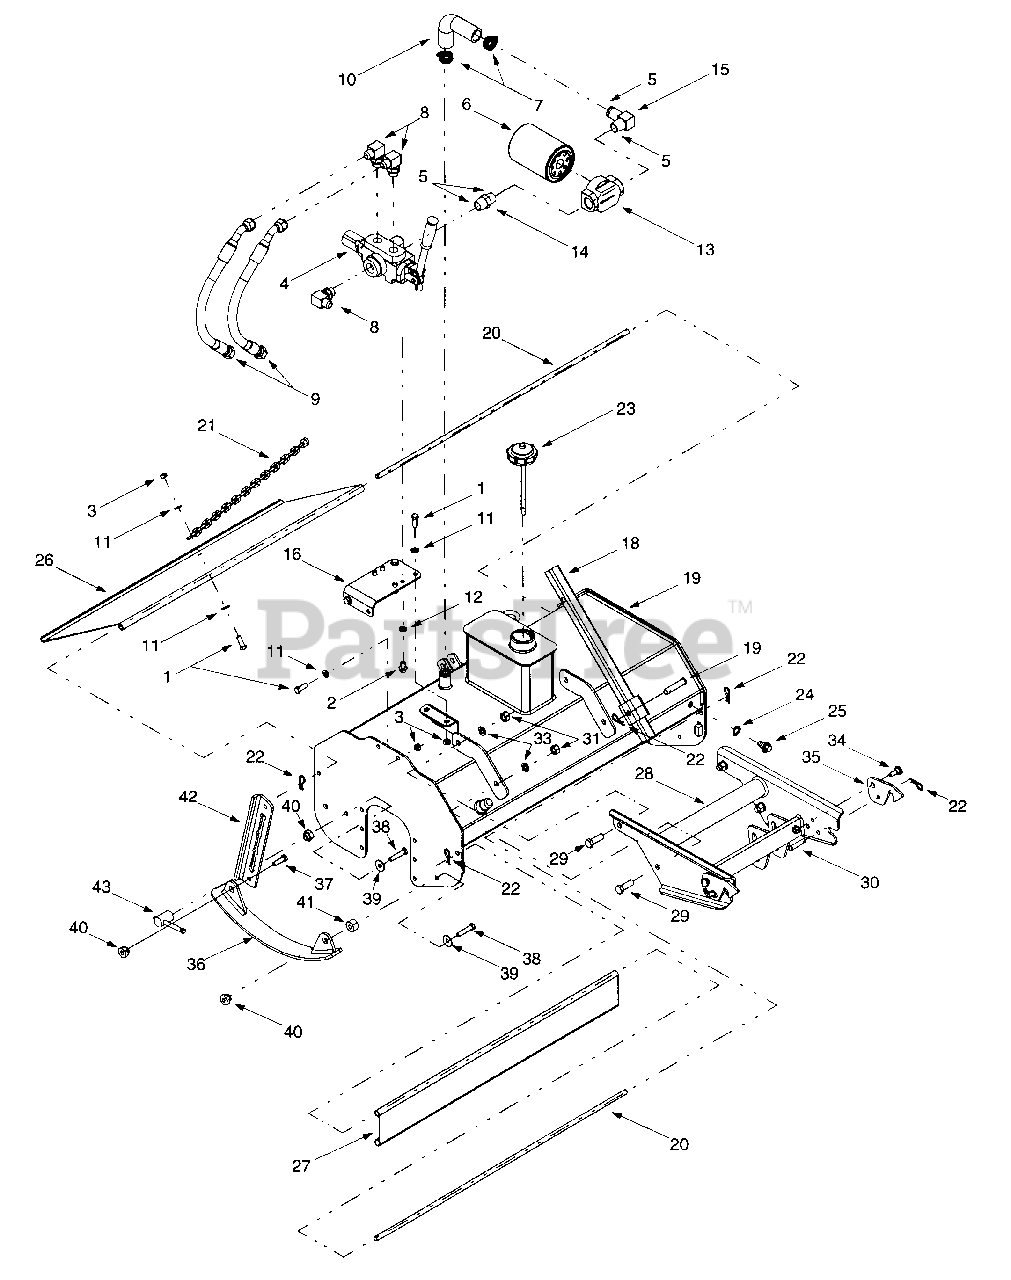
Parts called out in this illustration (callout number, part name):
1	Hex Cap Screw, 3/8-16 x 1.0
2	Shoulder Screw, 3/8-16 x.625
3	Hex Lock Nut, 3/8-16
4	Energy Hydraulic Valve
5	Locktite Hydraulic Sealant
6	Oil Filter
7	Adjustable Hose Clamp
8	90° Hydraulic Adapter, 7/8
9	Hydraulic Hose, 7/8-14
10	90° Hydraulic Hose, 1.37 x 1.0
11	Flat Washer, .375 x .738 x .063
12	Lock Washer, 3/8
13	Filter Housing
14	Hydraulic Adapter, 3/4 x 3/4
15	90° Hydraulic Adapter, 3/4 x 1.0
16	Valve Mounting Bracket
19	Clevis Pin, .50 x 2.0
20	Shield Pivot Rod
21	Chain, 24.37"
22	Internal Cotter Pin
23	Vented Tank Cap
24	Stat-O-Seal/O Ring
25	Drain Plug
30	Clevis Pin, 3/8 x 1.75
31	Hex Nut, 1/2-13
33	Lock Washer, 1/2
34	Shoulder Screw, .50 x .27, 3/8-16
35	Hitch Latch
36	Skid Bracket Assembly
37	Hex Cap Screw, 3/8-24 x 1.0
38	Hex Cap Screw, 3/8-24 x 1.75
39	Bell Washer, .396 x 1.14 x .095
40	Shoulder Nut, 3/8-24
41	Spacer, 1.0 x .380 x .64
42	Skid Adjuster Bracket
43	Adjuster Crank
